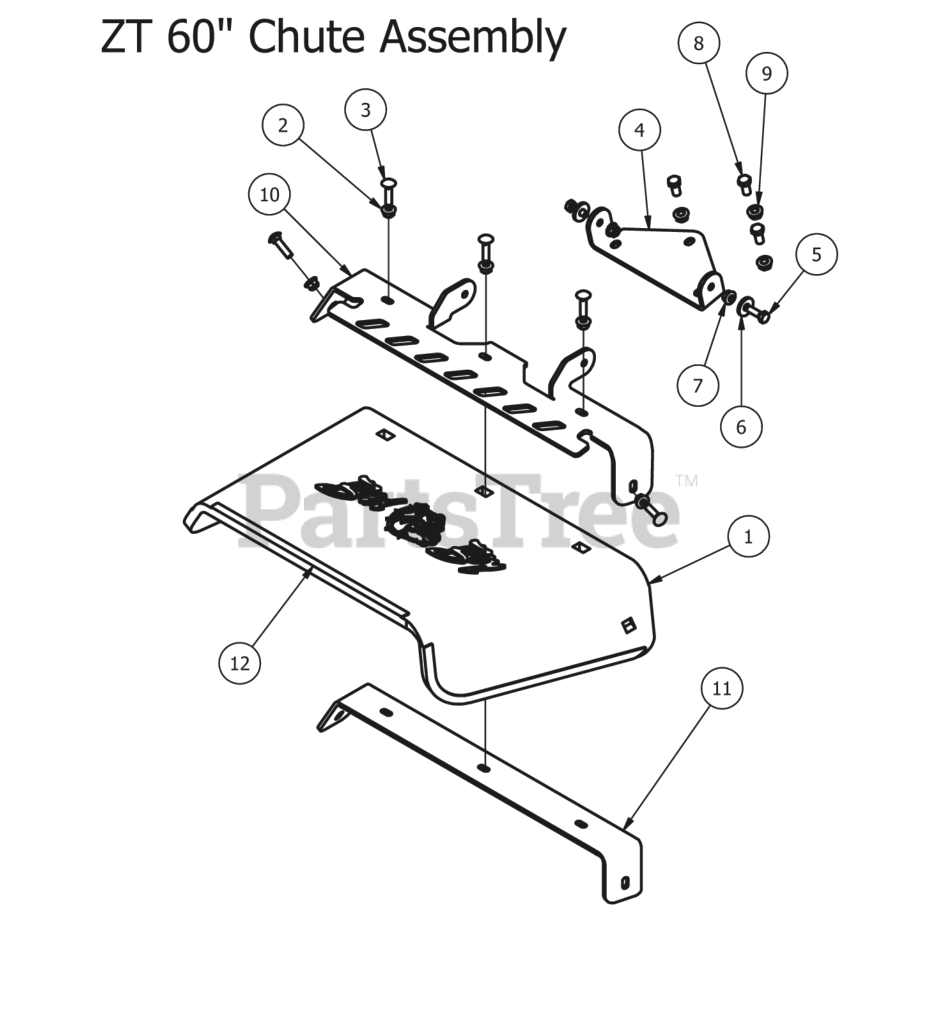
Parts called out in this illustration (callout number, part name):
1	Rubber Discharge Chute (Rubber Only)
2	5/16" Nylon Flange Nut
3	5/16" x 1 1/4" Carriage Bolt
4	Discharge Chute Hanger (deck mounted)
5	5/16" x 1" Bolt
6	.360 ID Plastic Washer
7	5/16" Nylon Flange Nut
8	3/8" x 3/4" Hex Bolt
9	3/8" Flange Nut
10	60" Upper Hanger Plate
11	60" Lower Hanger
12	60" Rubber Discharge Assembly Components 1,2,3,10,11
